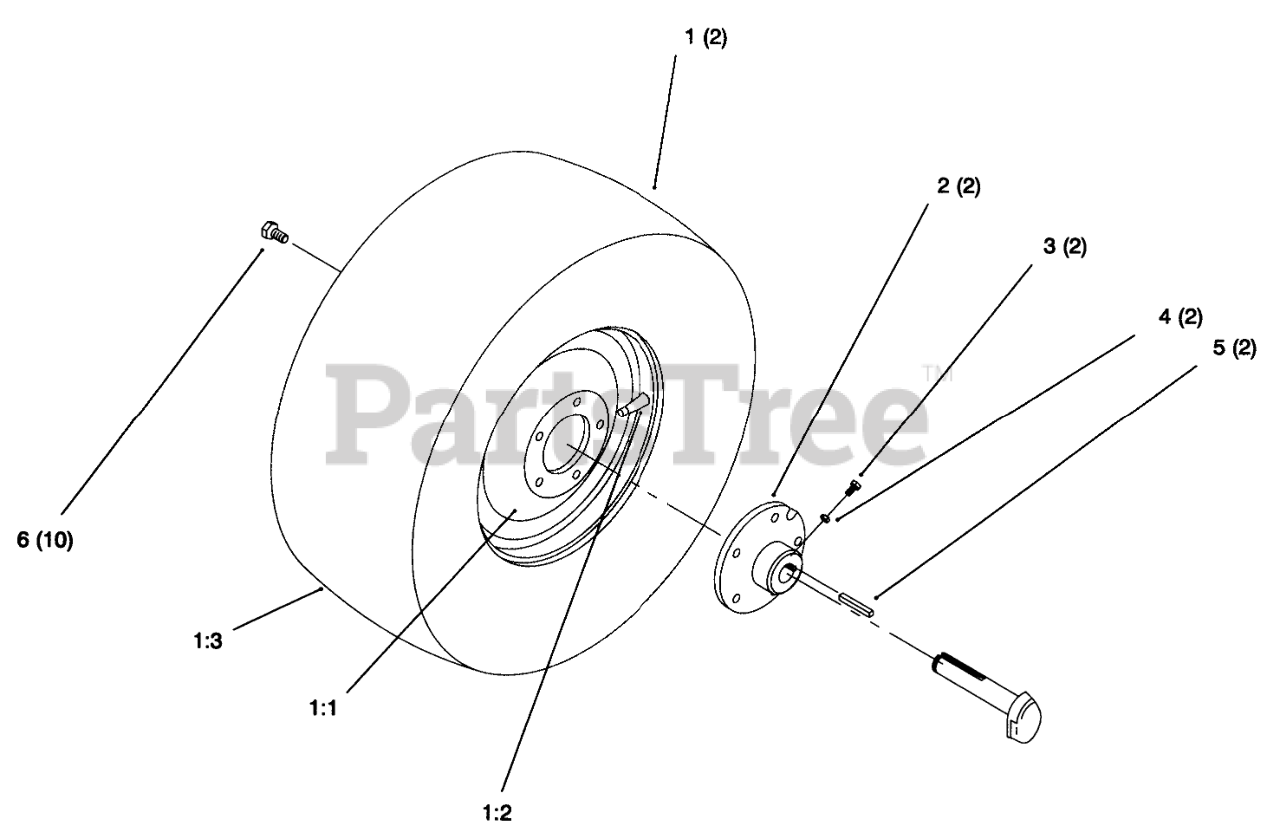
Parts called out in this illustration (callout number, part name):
1	Wheel AND Tire ASM
1:1	WHEEL
1:2	VALVE
1:3	TIRE
2	HUB-WHEEL
3	SCREW-SET, SQH
4	NUT-JAM
5	KEY-SQUARE
6	BOLT-LUG
